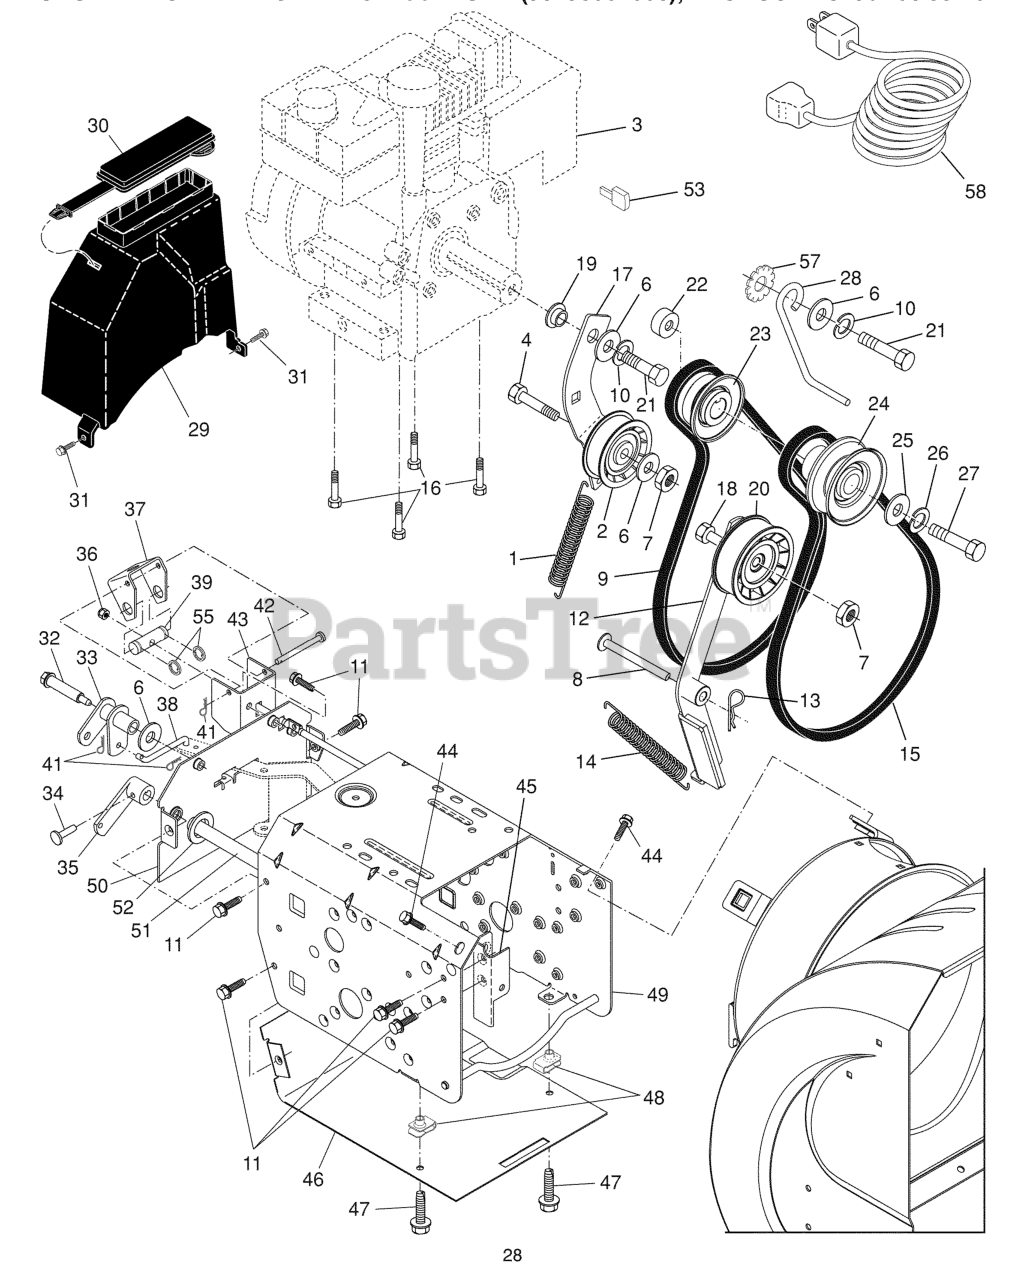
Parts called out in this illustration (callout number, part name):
1	RP SPRING, TRACTION IDLER
2	PULLEY.W/SPACER.2.25
4	BOLT.5/16-18X1-1/4 FULL.THREAD
6	STEEL WASHER
7	LOCKNUT 5/16-18
8	PIN, IDLER PIVOT
9	V-BELT, TRACTION DRIVE
10	WASHER.LOCK.HVY.HLCL.SPR.5/16
11	Screw, Hex Head 5/16-18 x 1/2
12	ARM PAD ASSY
13	RETAINER CLIP PM
14	SPRING, BRAKE
15	BELT.V.IMPELLER.DRIVE
16	BOLT 3/8-16X1-1/8
17	IDLER ARM
18	HEX BOLT
19	RP BUSHING, IDLER PIVOT
20	PULLEY.W/SPACER.2.75
22	SPACER.ENGINE.PULLEY
23	PULLEY,ENGINE TRACTION DRIVE
24	PULLEY, ENGINE IMPELLER DRIVE
25	WASHER, FLAT 3/8
26	LOCKWASHER
27	SCREW, HEX HD 3/8-24 X 1-3/8
28	BELT.GUIDE.RH
29	COVER.ASM.BELT/STORAGE
30	COVER.STORAGE.SNOW
31	SCREW
32	BOLT.SHOULDER.3/X.25
33	BRACKET.SHIFTER.PLATE.BZP
34	CLEVIS PIN
35	ARM, AUGER CONTROL
36	NUT.HEX.FLANGE.1/4
37	PLATE.CLUTCH.BZP
38	LINK, SPEED CONTROL
39	PLATE.CLUTCH.BZP
41	RETAINER CLIP
42	NUT.CENTERLOCK.5/16-
43	PLATE.SHIFTER.BZP
44	SCREW 3/8-16X1
45	BRACKET, IDLER PIVOT
46	PAN.BOTTOM.PLASTIC
47	SCREW, HEX HEAD, TAPPING
48	NUT.CENTERLOCK.5/16-
49	FRAME.WELD.PNT.003BGP
50	PLATE.REAR.SNOW.PNT.ORANGE
51	SHAFT, AUGER CONTROL
52	THRUST WASHER
53	KEY, SAFETY IGNITION
55	RETAINING RING LT
57	WASHER EXT TOOTH LOCK 5/16
58	CORD.ELECTRIC.10FT.120V.SNOW
